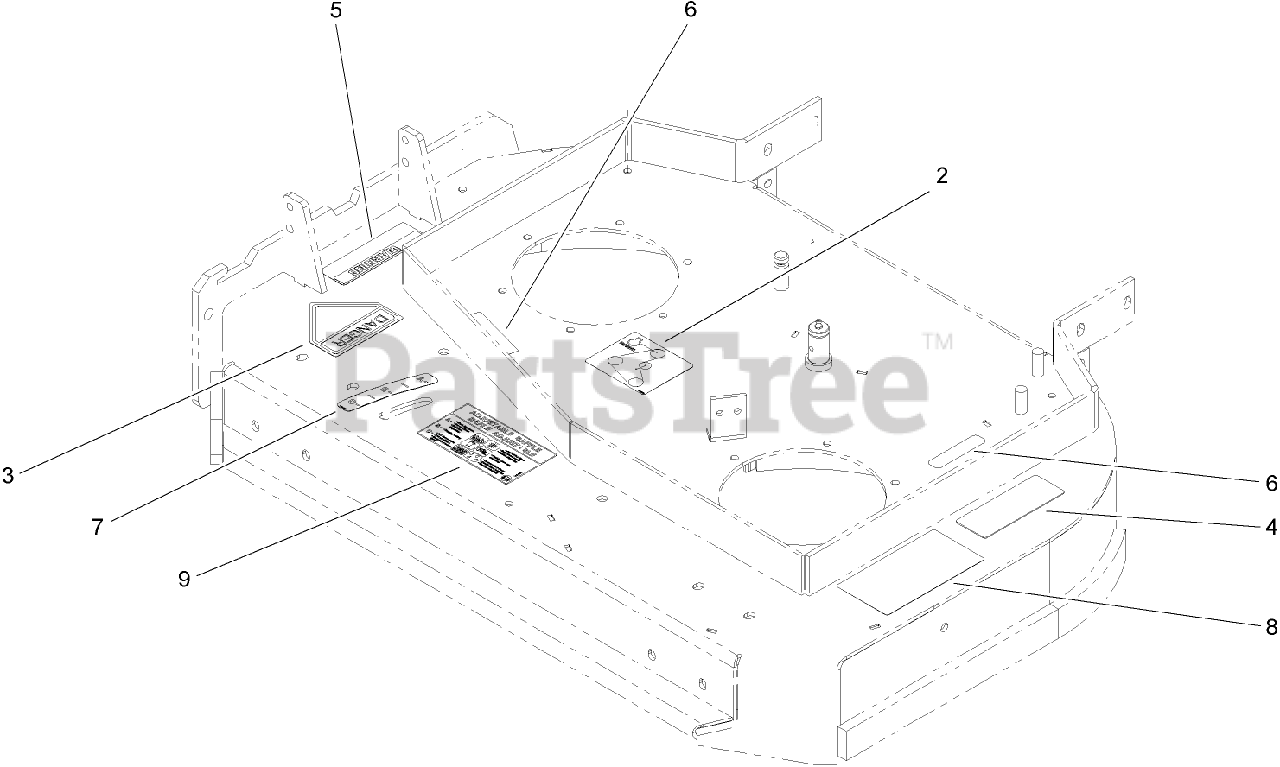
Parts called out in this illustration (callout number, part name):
2	DECAL-ROUTING, BELT
3	DECAL-DANGER
4	DECAL-TORQUE, BOLT
5	DECAL-WARNING
6	DECAL-COVER, MISSING
7	DECAL-SETTING, BAFFLE
8	DECAL-DANGER, THROWN OBJECT
9	DECAL-ADJUSTMENT, BAFFLE
